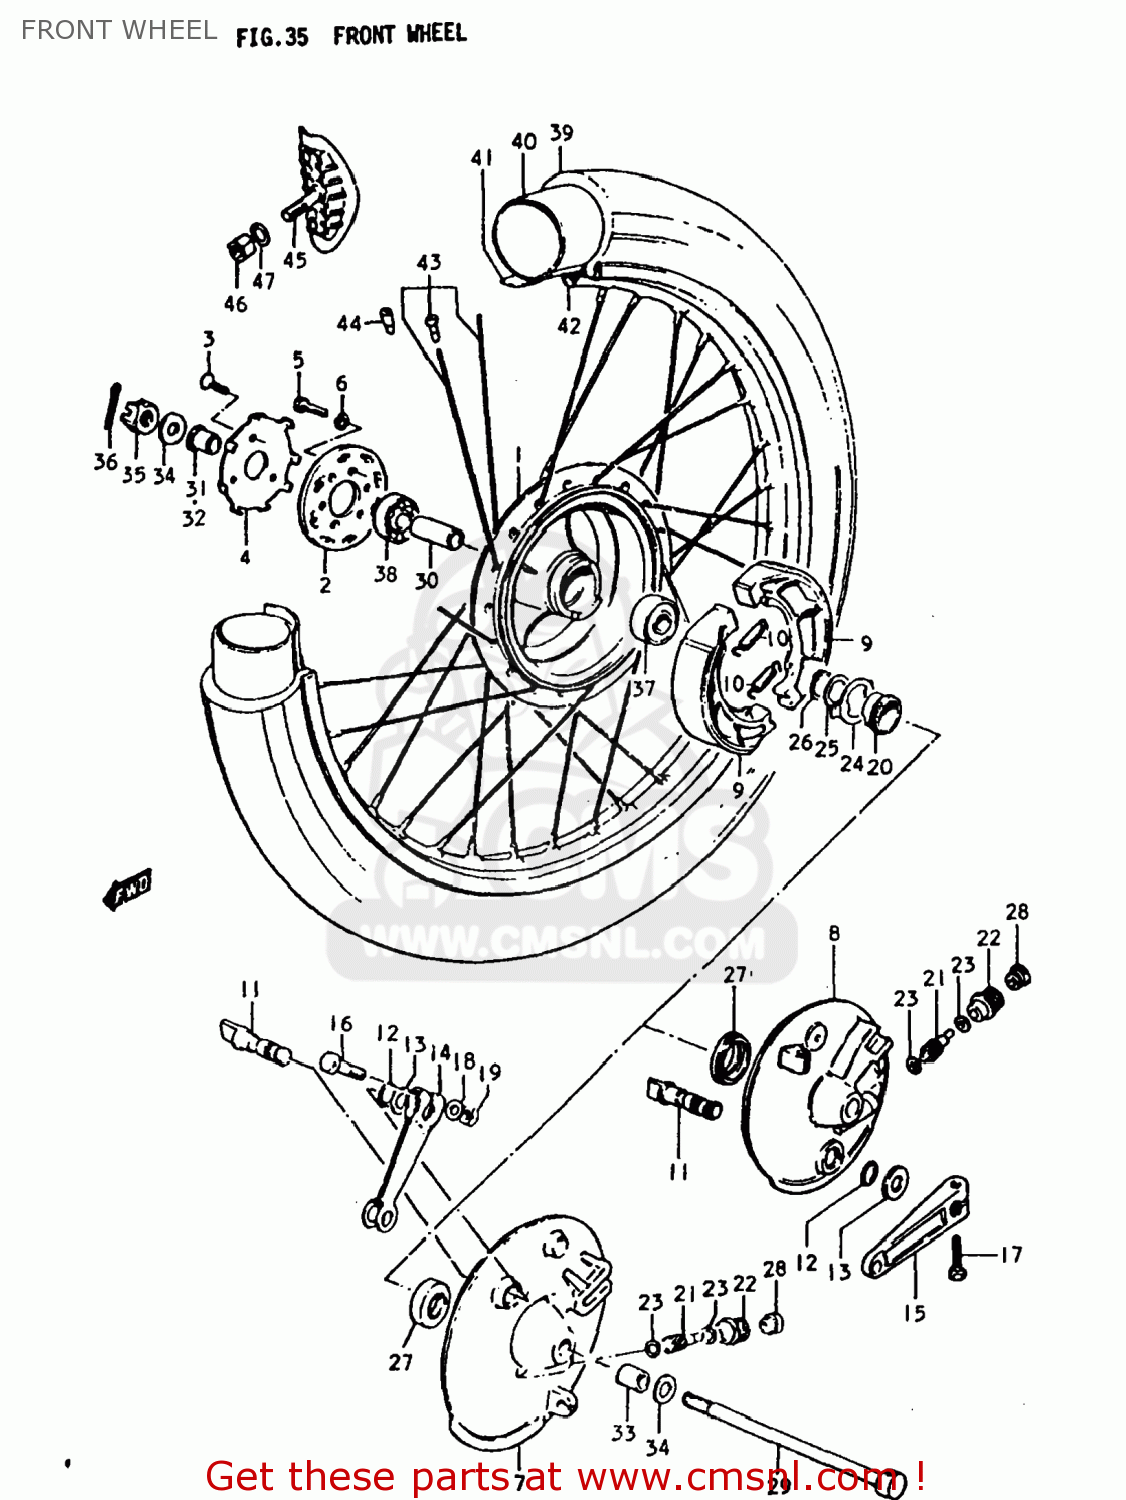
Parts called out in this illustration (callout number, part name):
1	DRUM,FRONT HUB
2	FLANGE,FR HUB,R
3	SCREW
4	RETAINER,FR HUB BEARING,R
5	BOLT, UPPER
6	LOCK WASHER
7	PANEL,FRONT HUB
8	PANEL,FRONT HUB
9	SHOE,BRAKE
10	SPRING
11	CAM,FRONT BRAKE
12	O-RING,BOSS
13	WASHER (15X24X1.6)
14	LEVER,FRONT BRAKE CAM
15	LEVER,FRONT BRAKE CAM
16	BOLT 6X40
17	BOLT
18	WASHER
19	NUT
20	GEAR,SPEEDOMETER
21	PINION,SPEEDOMETER
22	BUSHING,SPEEDOMETER PINION
23	WASHER (5.1X9X0.4)
24	DRIVER,SPEEDOMETER GEAR
25	WASHER(22.5X27X1)
26	CIRCLIP
27	OIL SEAL
28	SEAL,OIL(6X10X3)
29	AXLE,REAR
30	SPACER (12.6X19X52)
31	SPACER
32	SPACER,FR AXLE,R
33	SPACER(12X20X34.5)
34	WASHER
35	NUT 12MM
36	COTTER PIN
37	BEARING
38	BEARING, RH
39	TIRE,FRONT
40	TUBE
41	PROTECTOR,WHEEL,INNER
42	RIM,FRONT WHEEL
43	SPOKE SET,FRONT
44	BALANCER,WHEEL (50G)
45	STOPPER,BEAD
46	NUT
47	WASHER
